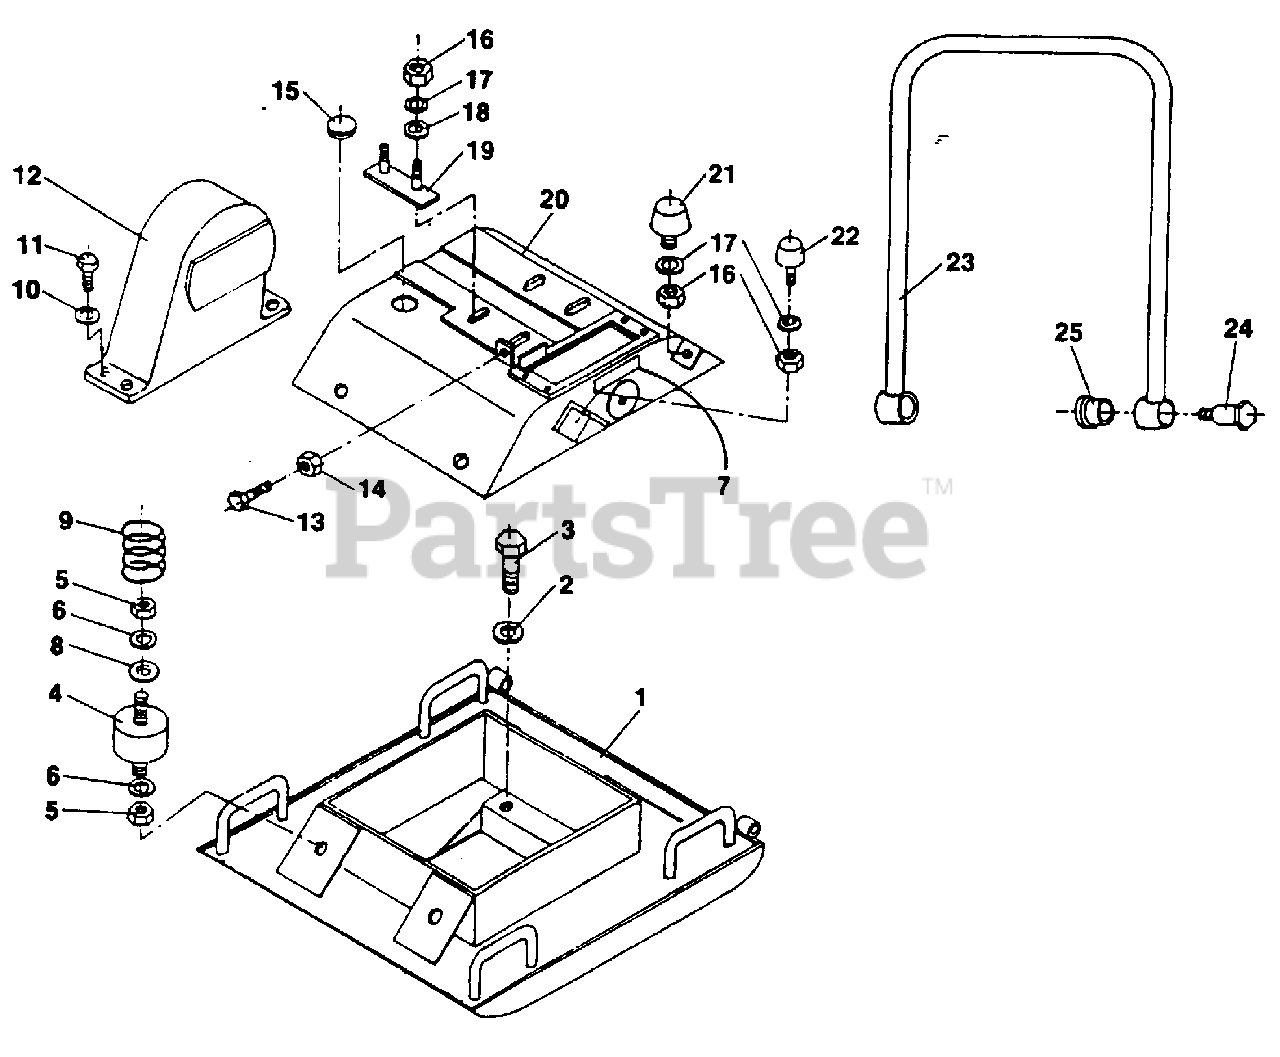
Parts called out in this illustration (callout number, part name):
1	PLATE- Vibration
2	WASHER- Spring (m16)
3	BOLT- Hex (m16 x 65)
4	ABSORBER- Shock
5	NUT- Hex (m12)
6	WASHER- Plate (m12)
7	DECAL- Caution
8	WASHER- Plate (m12)
9	SPRING- Earth
10	WASHER-Spring (m10)
11	BOLT-Hex (m10 x 25)
12	COVER- Belt
13	BOLT- Hex (m10 x 45)
14	NUT- Hex (m10)
16	NUT- Hex (m8)
17	WASHER- Spring (m8)
18	WASHER- Plate (m8)
19	SEAT- Engine
20	COVER- Vibration Plate
21	ABSORBER- Shock (OT-9)
22	ABSORBER- Shock
24	PIN- Bracket
25	RUBBER- Handle
